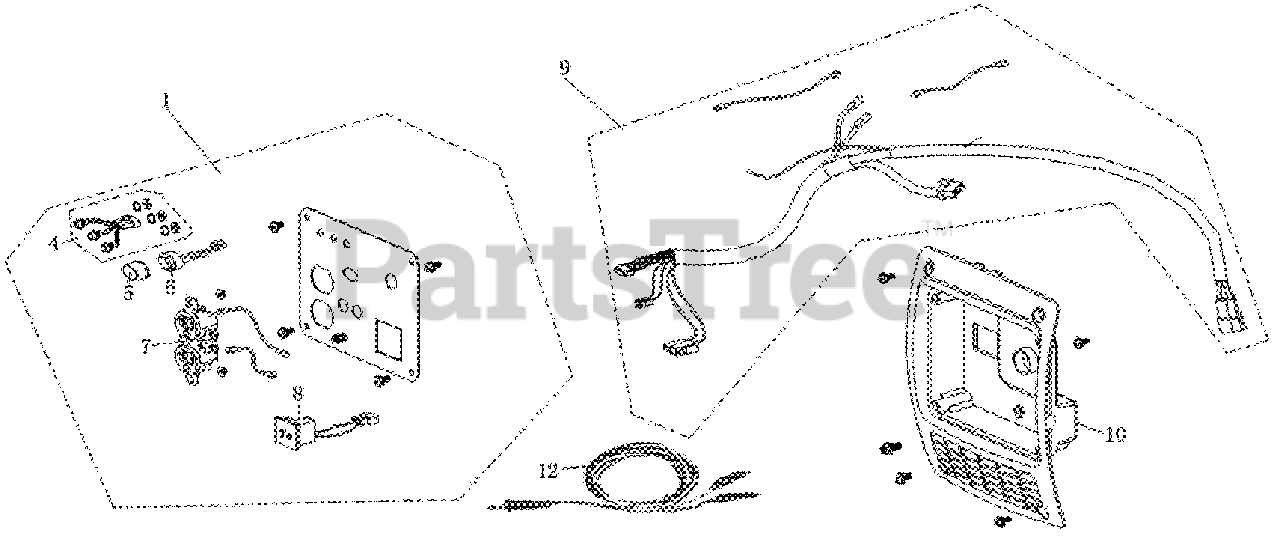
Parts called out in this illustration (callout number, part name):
1	COTRAL PANEL ASSY
4	LED INDICATOR LIGHT
5	GRID INSERTED DEACTIVATION SWITCH
6	DEACTIVATION SWITCH
7	POWER SOCKET COMBINATION
8	DC SOCKET (WITH FLOW DEVICE)
9	CABLE ASSEMBLY
10	PANEL SEAT
12	CONNECTING LINE
